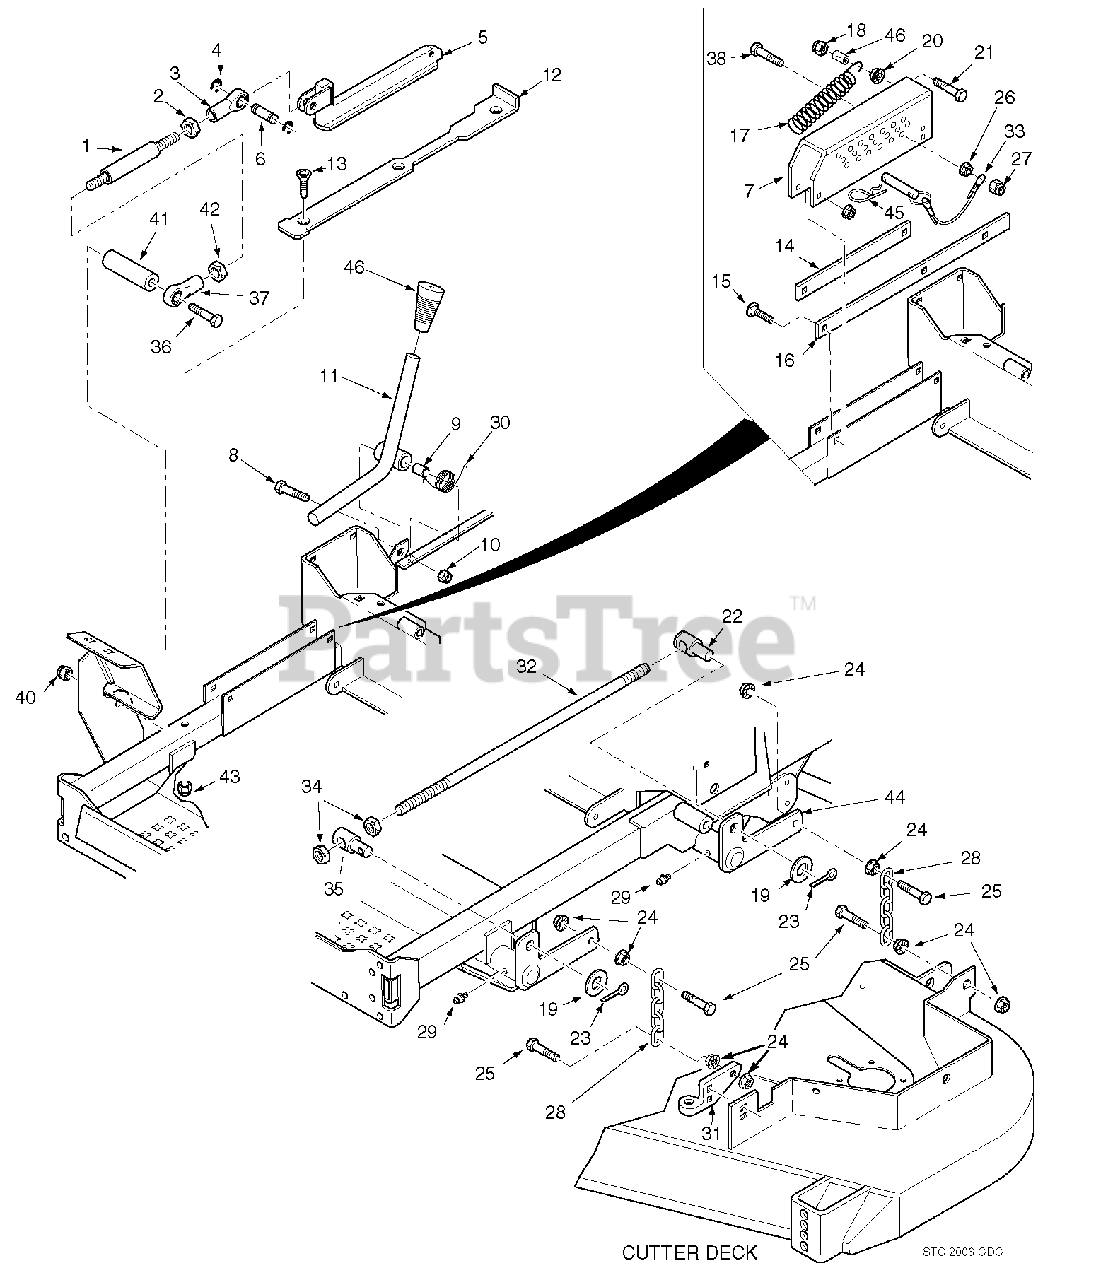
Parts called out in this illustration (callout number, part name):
1	Rod, Deck Lift Linkage
2	Nut, Jam 1/2-20 LH Thread
3	Rod End, 1/2-20 Female LH Thread
4	Retaining Ring, 1/2" Ext. "E"
5	Slide, Deck Height Adjust
6	Pin, Deck Lift
7	Bracket, Cutting Height Adjustment
8	Bolt, Hex Hd. 3/8-16 x 2-3/4"
9	Bushing .502" OD
10	Nut, Elastic Stop 3/8-16
11	Lever, Deck Latch
12	Slide, Cutting Height
13	Capscrew, 5/16-18 x 3" Flathead Hex Socket Grd. 8
14	Guide, Short
15	Bolt, Carriage 5/16-18 x 1"
16	Guide, Long
17	Spring, Helper
18	Nut, 3/8-16 Center Lock
19	Flatwasher, 5/8 (.656 x 1.312 x .095")
20	Nut, 3/8-16 Serr. Flng.
21	Bolt, Hex Hd. 3/8-16 x 1-1/4"
22	Swivel Joint LH
23	Cotter Pin, 3/16 x 1"
24	Nut, Serr. Flng. 3/8-16
25	Bolt, Hex Hd. 3/8-16 x 1-1/2"
26	Nut, Serr. Flng. 3/8-16
27	Nut, Elastic Stop 3/8-16
28	Chain
29	Grease Fitting, 1/4-28 Self Tap
30	Torsion Spring
31	Lever Assy., Deck Level
32	Stud, 1/2-13 x 20"
34	Nut, 5/8-11 UNC
35	Swivel Joint RH
36	Bolt, Hex Hd. 1/2-13 x 5"
37	Rod End, 1/2-20 Female RH Thread
38	Bolt, Hex Hd. 3/8-16 x 3-1/2"
39	Spacer
40	Locknut, 1/4-20
41	Spacer
42	Nut, 1/2-20 UNF-2B RH Thread
43	Nut, Elastic Stop 5/16-18
44	Lift Bellcrank Weldment, LH Rear
45	Hair Pin Cotter, .177" x 3-1/4"
46	Grip, Deck Latch Lever
